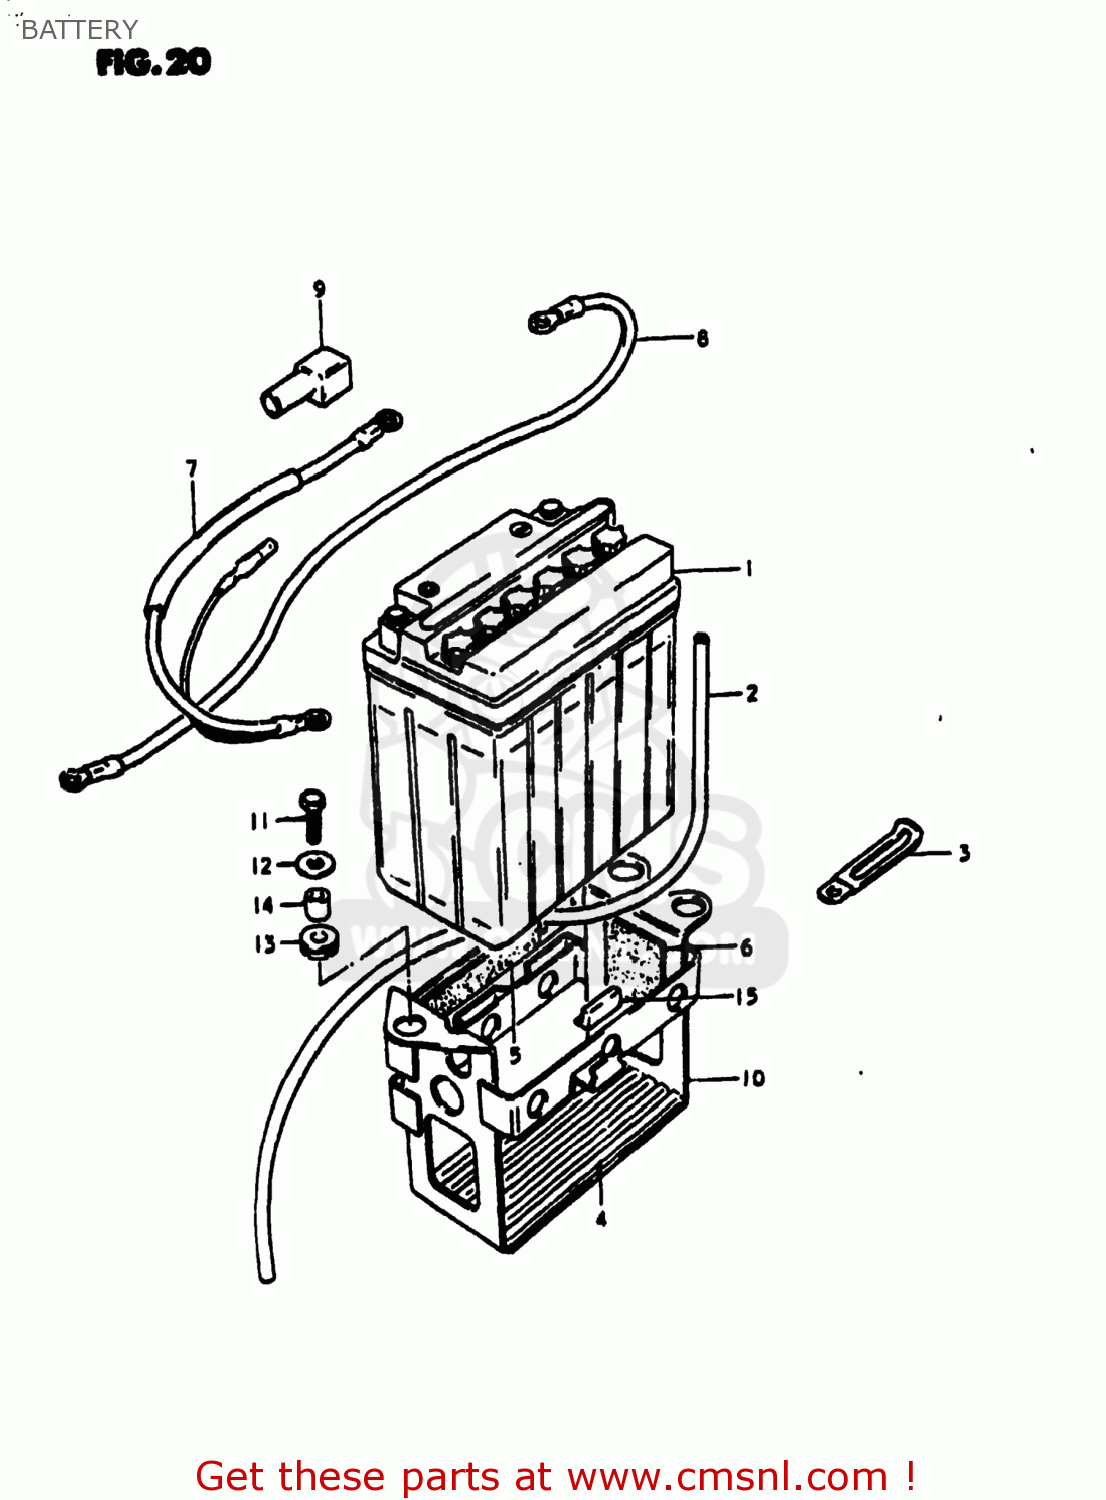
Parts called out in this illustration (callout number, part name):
1	BATTERY ASSY (12V)
2	HOSE,BATTERY EXHAUST
3	CLAMP L:35
4	PROTECTOR,BATTERY
5	PROTECTOR(20X90)X4
6	PROTECTOR,BATTERY
7	WIRE,BATTERY PLUS
8	LEAD WIRE,BATTERY(-)
9	CAP,TERMINAL
10	HOLDER,BATTERY
11	BOLT, UPPER
12	WASHER
13	CUSHION
14	SPACER(6.1X9X7.5)
15	CUSHION,FRAME COVER
